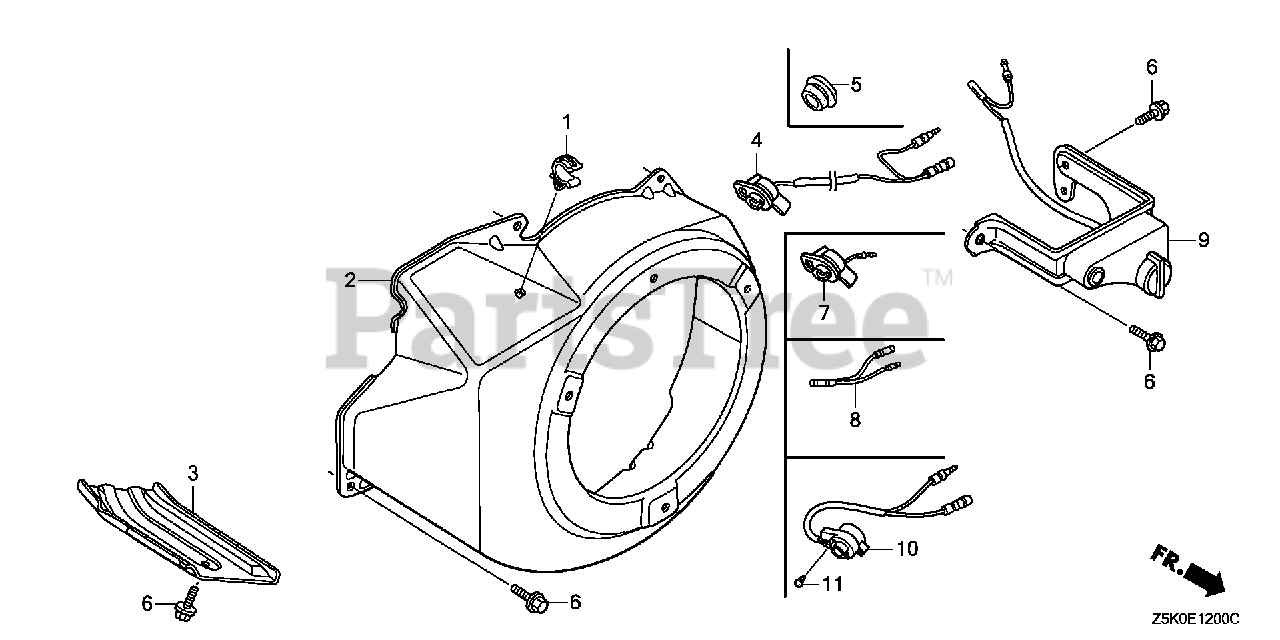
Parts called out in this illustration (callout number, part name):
1	CLIP, TUBE
2	COVER, FAN *R280* (POWER RED)
6	BOLT, FLANGE (6X12) (CT200)
10	SWITCH ASSY., ENGINE STOP
11	SCREW, TAPPING (3X6) (PO)
